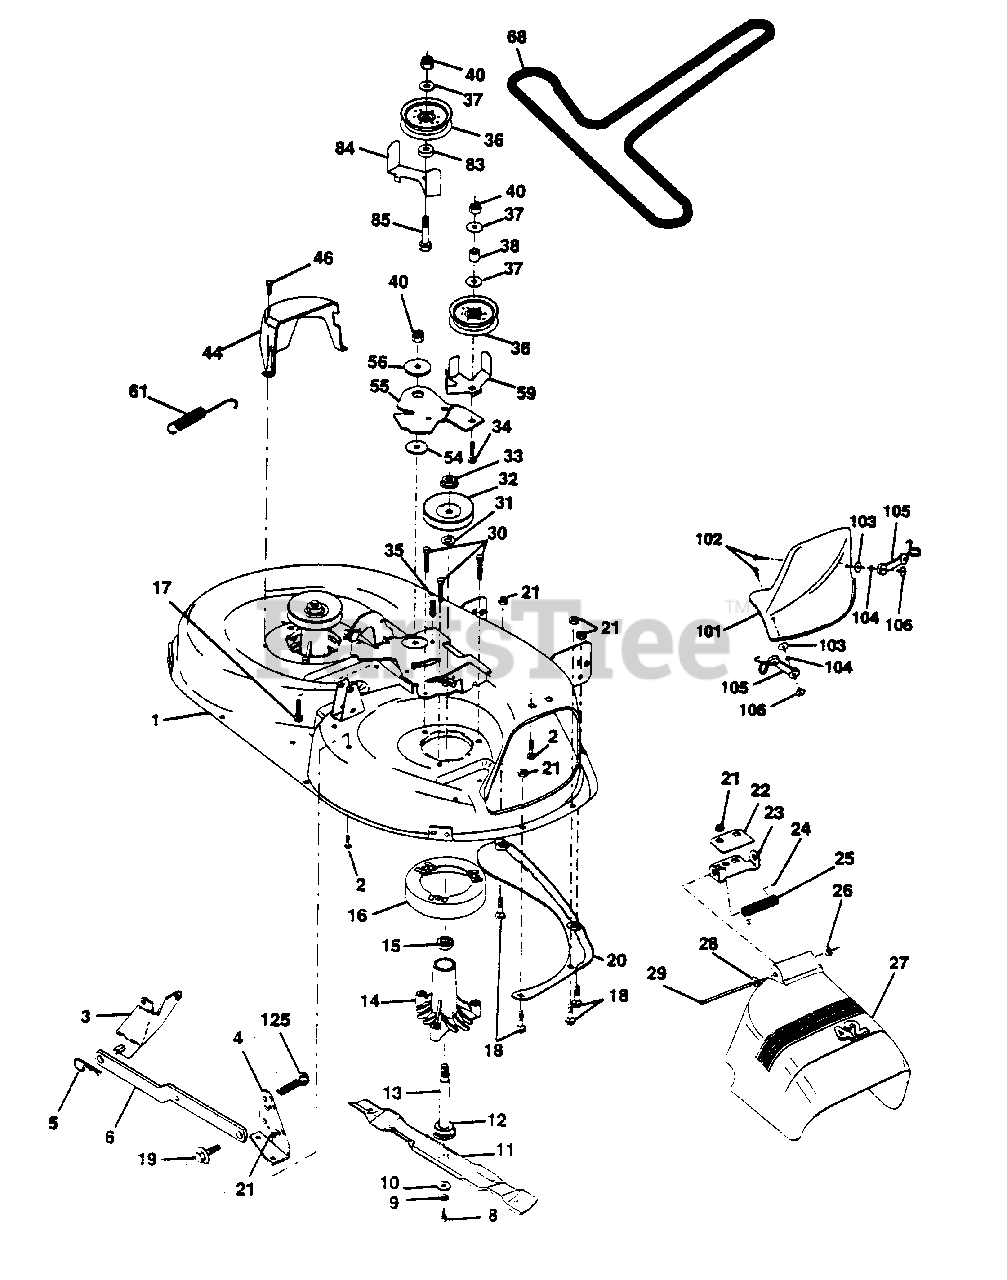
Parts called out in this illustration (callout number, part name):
1	Deck Asm Mower 42"
2	Bolt Rdhd Sqnk 5/16-18unc X3/4
3	Bracket Asm Fr Sway Bar
4	Bracket Asm Deck Sway Bar 42"
5	Retainer Spring
6	Arm Suspension Rear
8	Bolt 3/8-24x1 25 Gr8 Patched
9	Washer Lock Hvy 3/8 Unplated
10	Washer Hard Blade Mower Vented
12	Bearing Ball #6204 (Mandrel)
13	Shaft Asm W/lower Bearing
14	Housing Mandrel Vented(machd)
15	Bearing Ball Mandrel
16	Stripper Mower Vented
17	Bolt Rdhd Sqnk 3/8-16 X 2-1/4
18	Bolt Rdhd Sqnk 5/16-18 X 5/8
19	Bolt Shoulder 5/16 - 18
20	Baffle Vortex 42
21	Nut Crownlock 5/16-18
22	Stiffener Bracket 42" deck
23	Bracket Deflector Mower 42"
24	Cap Sleeve 80x 112 Blk Mower
25	Spring Torsion Deflector 2 52
26	Nut Push Phos & Oil
27	Shield Deflector Mower 42" Blk"
28	Washer 11/32 X 5/8 X 16 Ga
29	Rod Hinge 42" 6 75 Wlg
30	Screw Thdrol Hex Head
31	Washer Spacer Mower Vented
32	Pulley Mandrel 42"
33	Nut Flg Top Lock Cntr B 9/16
34	Bolt Rdhd 3/8-16uncx1-3/4 Gr5
35	Fastner Christmas Tree
36	Pulley Idler Flat 3 060
37	Washer 13/32 X 13/16 X 16 Ga
38	Spacer Spring Stop Idler
40	Nut Crownlock 3/8-16 UNC
44	Guard Mandrel LH Black
46	Screw Hex Thd Cut 1/4-20x5/8 T
54	Washer Hardened
55	Arm Idler 42" mower LT/YT
56	Spacer Retainer Pm Mower
59	Guard TUV Idler
61	Spring Ext. Elect. Clutch 38/42"
83	Washer Sintered
84	Keeper Belt Idler Fixed
85	Bolt Rdhd Sqnk 3/8-16 x 2-1/4
101	Cover Mulching 42" Black
102	Screw
104	Washer Lock #10
105	Latch Asm Bagger
106	Nut Weld .327/.304 # 10-24
125	Pin Cotter 1/4 x 1 plated
